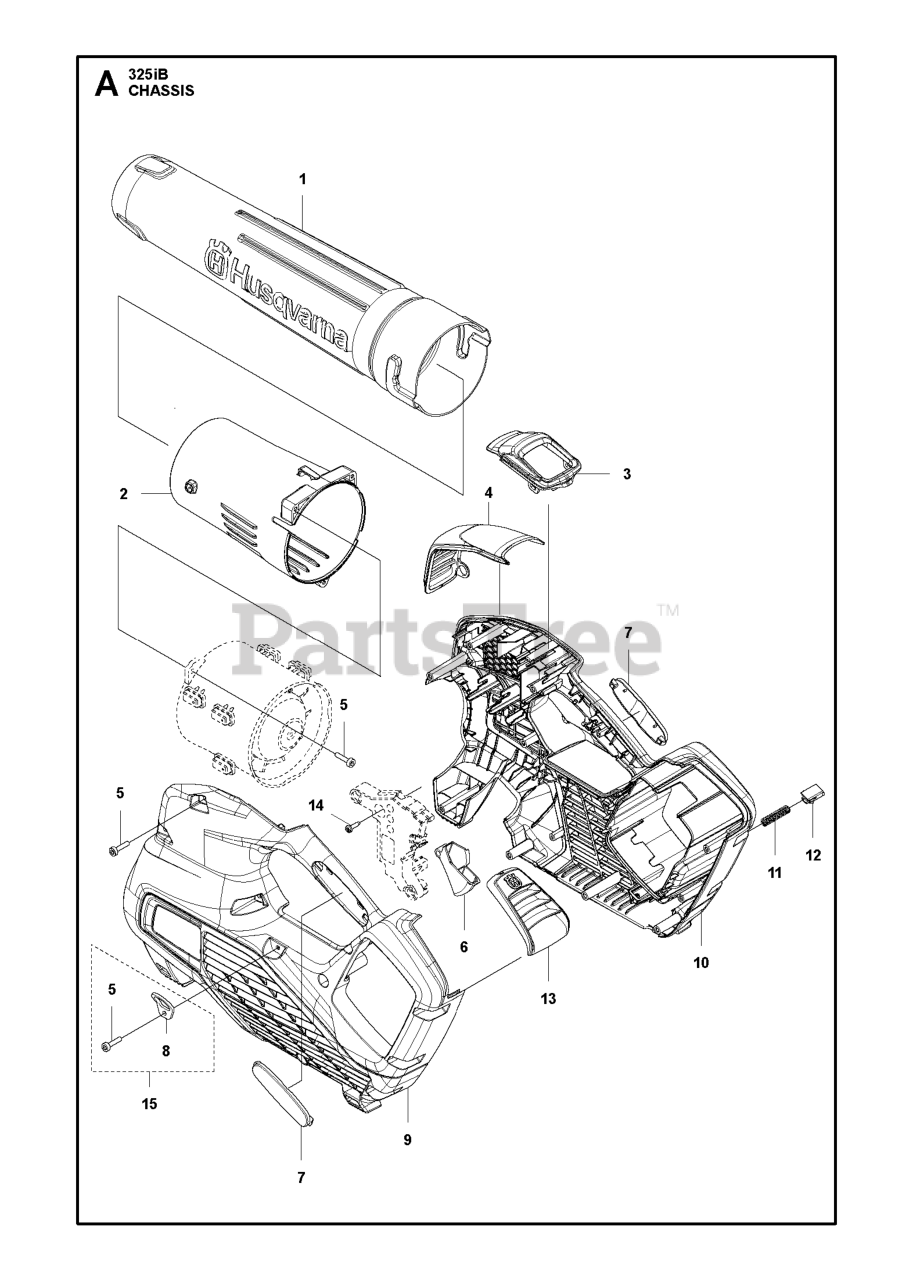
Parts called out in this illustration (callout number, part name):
2	TUBE FAN SYSTEM
3	FRAME KEYPAD
4	FRONT COVER
5	SCREW ITXSCT PW4.2X18 10.9 ZN
6	THROTTLE CONTROL
7	HANDLE INSERT GREY
9	HOUSING LEFT
10	HOUSING RIGHT
11	SPRING PUSH OUT
12	PUSH BUTTON
14	SCREW CITXPANT
15	KIT EYELET
